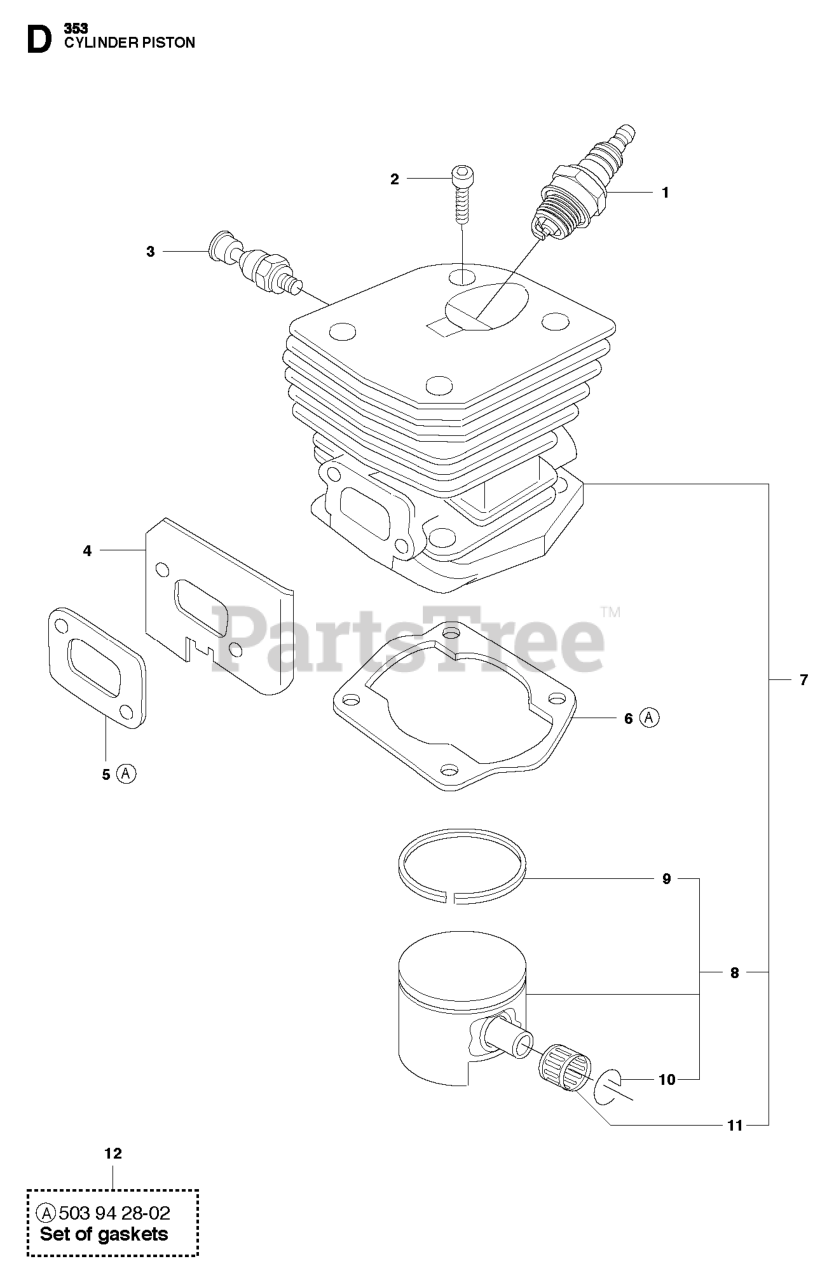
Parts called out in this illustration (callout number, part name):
1	SPARK PLUG RCJ7Y
2	SCREW MC6S 5X25
3	DECOMPRESSION VALVE
7	CYLINDER ASSY
8	PISTON
9	PISTON RING
10	LOCKING RING
11	NEEDLE BEARING
12	GASKET SET
